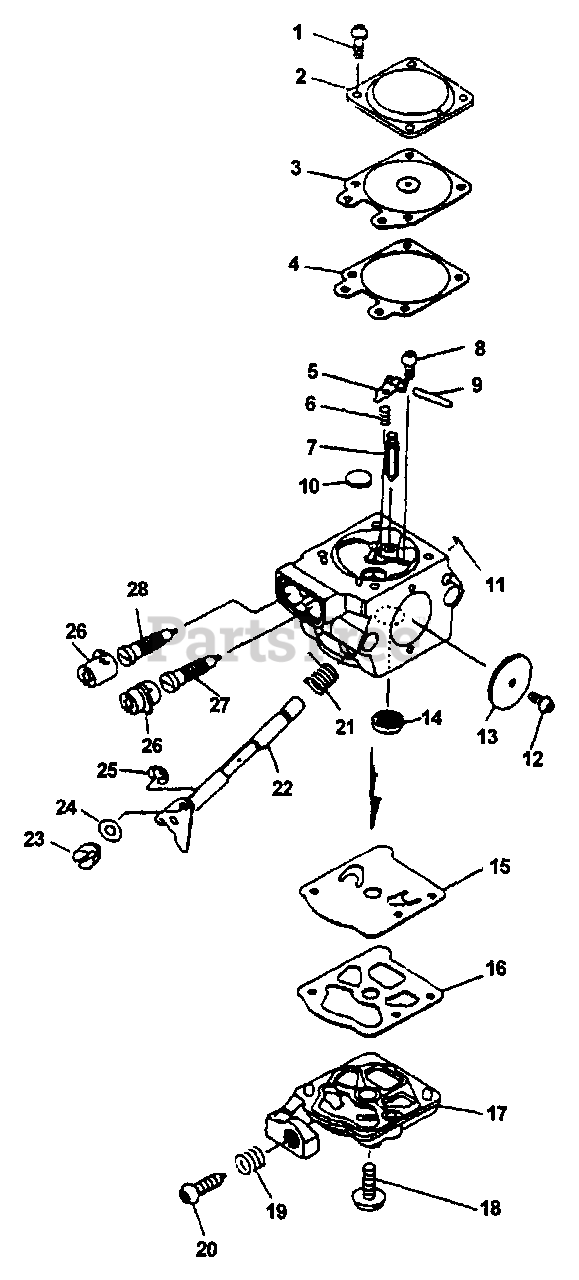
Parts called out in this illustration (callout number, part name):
1	SCREW
2	COVER, METERING
3	DIAPHRAGM, METERING
4	GASKET, METERING
5	LEVER, METERING
6	SPRING, METERING LEVER
7	VALVE, INLET NEEDLE
8	SCREW, METERING LEVER PIN
9	PIN, METERING LEVER
10	PLUG, WELCH
11	RING, RETAINING
13	VALVE, THROTTLE
14	STRAINER
15	DIAPHRAGM, PURGE
16	GASKET, PURGE
17	COVER, PUMP
18	SCREW, PUMP COVER
19	SPRING, IDLE ADJUST
20	SCREW, IDLE ADJUST
21	SPRING, THROTTLE RETURN
22	SHAFT, THROTTLE
25	RING, RETAINING
26	CAP, LIMITER
27	NEEDLE - LOW SPEED
28	NEEDLE - HIGH SPEED
